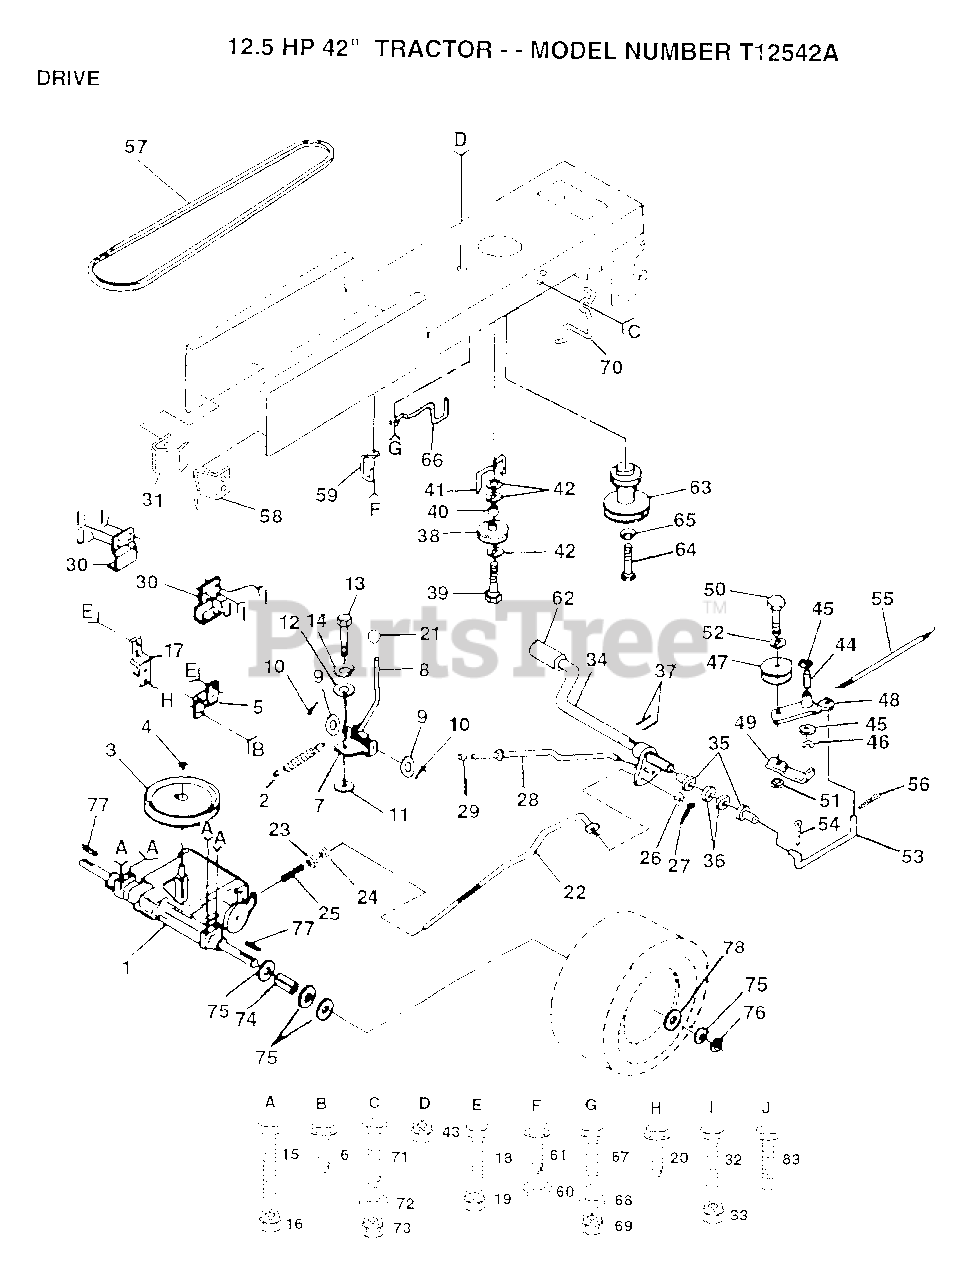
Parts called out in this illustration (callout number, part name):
3	PULLEY TRANS
5	STRAP TORQUE
6	SCREW
8	SHIFT ROD
9	WASHER
10	PIN COTTER 1/8
11	WASH-SHFT PLT LT
12	WASHER LT
14	LOCKWASHER
15	BOLT
17	STRAP TORQUE
20	SCREW
21	CONTROL KNOB LT
22	BRAKE ROD
23	NUT
24	NUT
25	SPRING ROD LT
26	WASHER
27	COTTER PIN
28	PARKING BRAKE ROD
30	TRANSAXLE MTG BKT
31	"KEEPER,BELT LH T"
32	BOLT
35	NYLON BEARING
36	WASHER LT
38	PULLEY.IDLER.FLAT
39	BOLT
40	SPACER T
41	BELT KEEPER LT
42	WASHER
44	"LY, BEARING"
45	WASHER LT
46	KLIP RING
48	ARM IDLER
49	RETAIN BELT
52	WASHER
53	"LINK, CLUTCH T"
54	COTTER PIN
55	"SPRING, RETURN LT"
56	COTTER PIN
57	BELT.V.GDRIVE.95
58	"KEEPER,BELT RH T"
60	WASHER
61	SCREW
62	PEDAL COVER T
64	BOLT
65	LOCKWASHER
66	KEEPER.BELT.ENG.L
67	BOLT
68	WASHER
70	KEEPER BELT ENG
71	BOLT
72	WASHER
74	SPACER LT
75	WASHER
76	E-RING LT
77	SQUARE KEY
78	WASHER
83	SCREW
